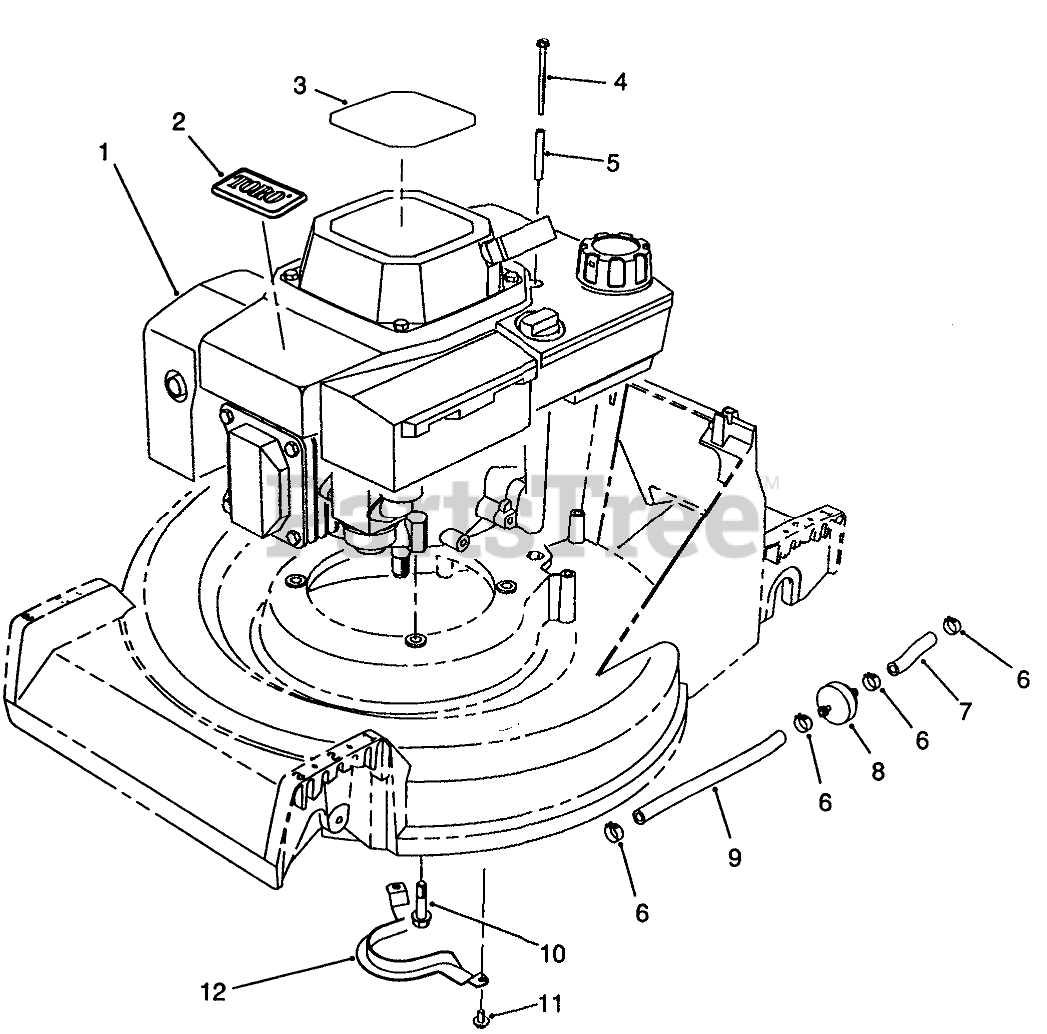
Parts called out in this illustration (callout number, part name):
1	ENGINE ASSY BBC OHV SU
2	TORO LOGO PLT
3	DECAL-HV INT'L
4	THRD FORMING SCREW
5	TUBULAR SPACER
6	CLAMP-FUEL LINE
7	LINE-GAS
8	FILTER-FUEL
9	HOSE-FUEL
10	SCREW-HWHTF
11	SCREW-HWHTF
12	Guide-Belt
